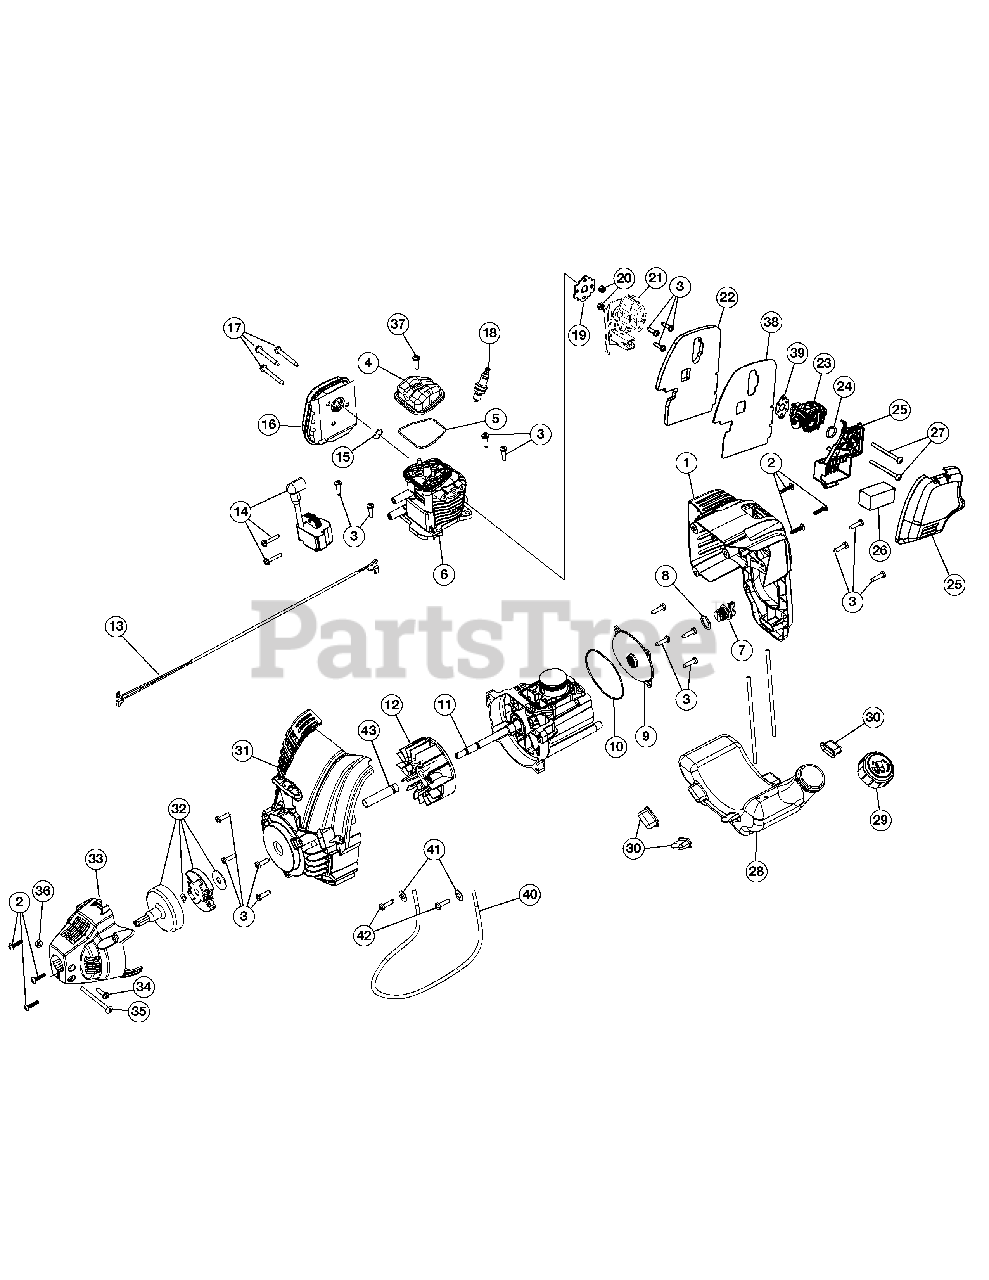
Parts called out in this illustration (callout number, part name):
1	Engine Cover Assembly (Incl. 2 & 3)
2	Cover Screw
4	Rocker Cover
5	Rocker Cover O-Ring
6	Cylinder Assembly (Incl. 3 & 5)
7	Oil Plug (Incl. 8)
8	Oil Plug O-Ring
9	Crankcase Cover
10	Crankcase Cover O-ring
11	Crankcase Assembly (Incl. 10)
12	Flywheel Assembly
13	Lead Wires
14	Module Assembly
15	Muffler Gasket
16	Muffler Assembly (Incl. 15 & 17)
17	Muffler Screw
18	Spark Plug
19	Insulator Gasket
22	Heat Shield
23	Carburetor
25	Air Cleaner Cover Assembly (Incl. 26)
26	Air Filter
28	Fuel Tank Assembly w/Fuel Lines (Incl. 29)
30	Fuel Tank Pads
31	Starter Housing Assembly (Incl. 3)
32	Clutch Assembly
33	Clutch Cover (Incl. 2)
34	Anti-Rotation Screw
35	Clamp Screw
37	Rocker Cover Screw
40	Foot Stand (Incl. 41 & 42)
